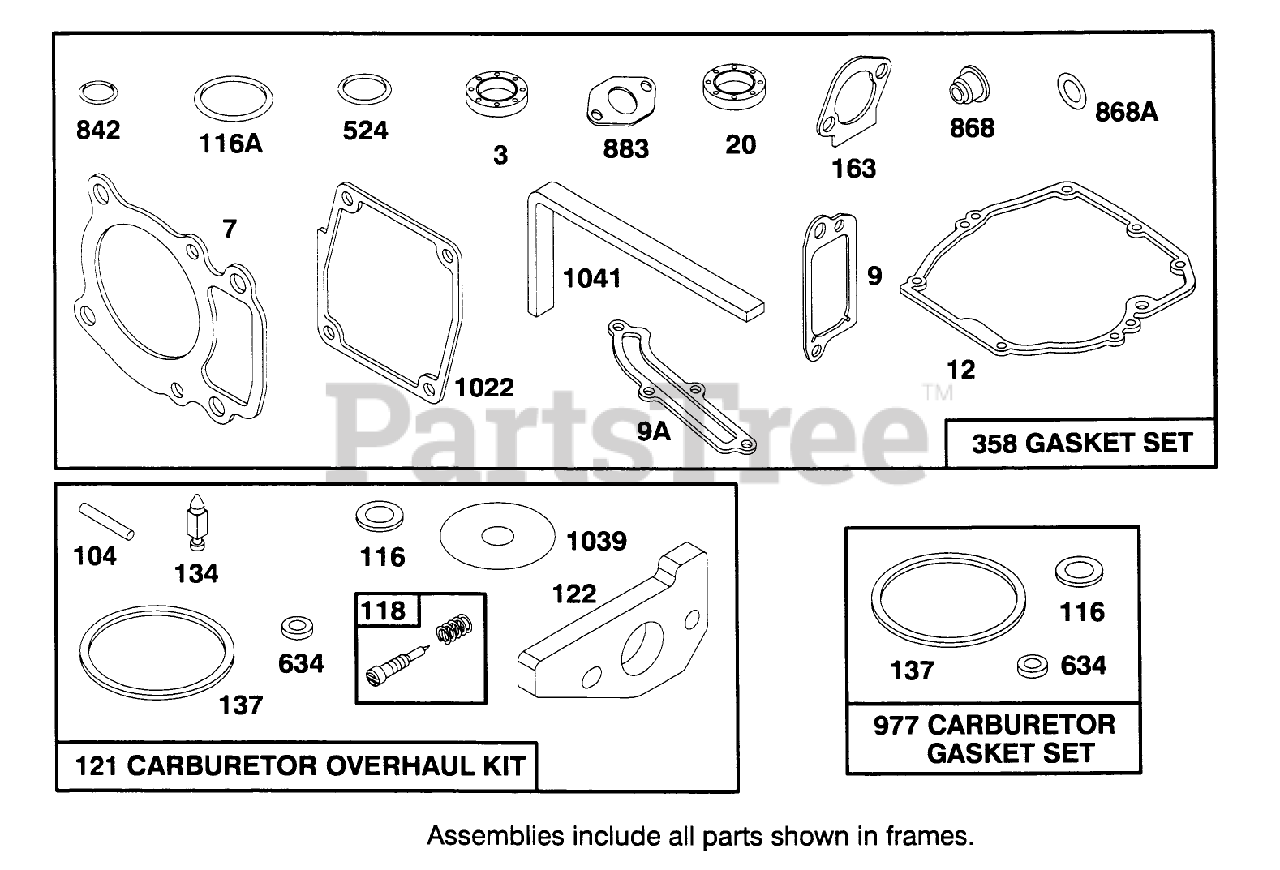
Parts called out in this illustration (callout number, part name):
7	CYLINDER HEAD GASKET
12	ENGINE BASE GASKET
20	SEAL-OIL
116	SEALING GASKET
116A	O RING SEAL
118	VALVE KIT - NEEDLE
121	CARBURATOR OVERHAUL KIT
122	ADAPTER ASSEMBLY
134	VALVE-FLOAT
137	FLOAT BOWL GASKET
163	AIR CLEANER GASKET
358	GASKET SET
524	O-RING
842	O-RING
977	CARBURATOR GASKET SET
1022	ROCKER COVER GASKET
1039	VENT TUBE
